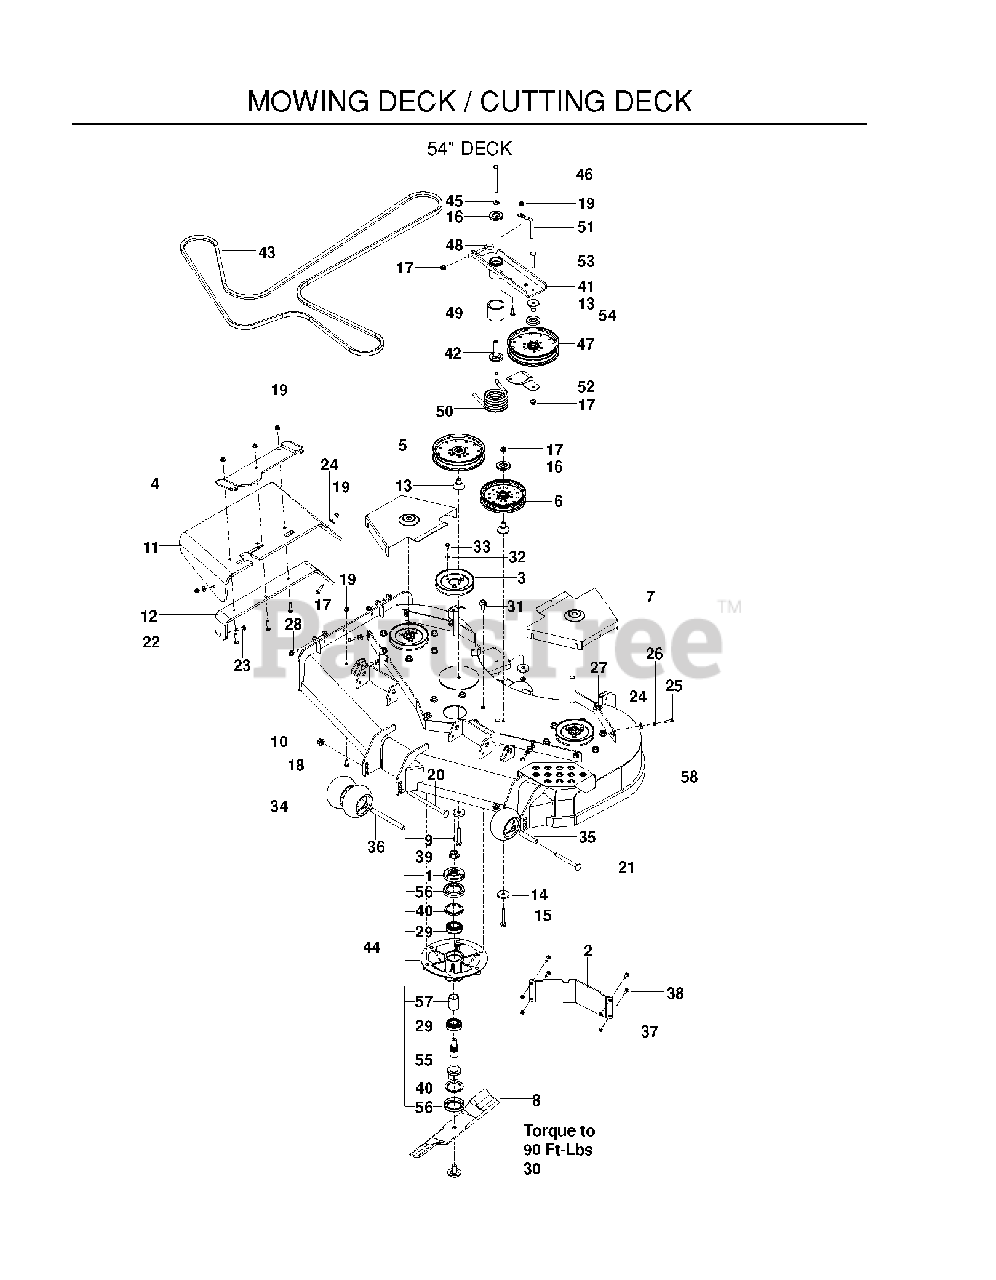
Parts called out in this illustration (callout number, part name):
1	HUB - PULLEY
2	BAFFLE, DIVERTER 54"/60" LH
3	PULLEY - 5.93 OVER PINS
4	BRKT - CHUTE MTG BLACK
5	PULLEY - 7" NARROW
6	PULLEY IDLER, 6" NARROW
7	SHIELD, BELT, 60" BLUE
9	ZERK
10	NUT, 1/2-13 HEX FLG NYLOC ZD
11	CHUTE, DISCHARGE 48-52
12	BRKT, CHUTE SUPPORT BLACK
13	BEARING, IDLER ARM
14	SPINDLE WASHER
15	HHFS 3/8-16 X 2 3/4
16	DUST SHIELD
17	NUT 3/8-16 HEX FLG NYLOC ZD
18	HHFS 5/16-18 X 3/4
19	5/16-18 NYLOC FLANGE NUT
20	RHSNB 1/2-13 X 8 GR5 ZD
21	RHSNB 1/2-13 X 4.75 GR5 ZD
22	RHSNB 5/16-18 X 1-1/2 GR 5 ZD
23	BOLT, CARRIAGE 5/16X1-1/4
24	WASHER 5/16 FLAT
25	HCS 5/16C X 1
26	WASHER 5/16 LOCK
27	U-CLIP 5/16-18 NUT RETAINER
28	HHFS 3/8-16 X 1 GRD 5 ZD
29	BEARING - 206KRR8
30	BLADE BOLT/WASHER
31	HHFS 1/2-13 X 1 GR5 ZD
32	WASH 5/16 DISC SPRING ZD
33	HCS 5/16-18 X 1/2 GR 5 ZD
34	ROLLER, GAUGE .635 BORN
35	TUBE, ROLLER AXLE
36	TUBE, ROLLER AXLE LONG
37	NUT 1/4-20 NYLOC
39	NUT FLANGE 3/4-16
40	V-RING, 55MM
41	ASSY, IDLER ARM, PZ
42	BEARING, IDLER PIVOT
43	BELT, "B", 169.75
44	SPINDLE ASM. 10"
45	WASHER, 3/8 THICK
46	HCS 3/8-16 X 4-1/2 GR 8 ZD
47	PULLEY - IDLER 7"
48	EYE BOLT, 3/8 X 4"
49	SPACER, IDLER PIVOT
50	SPRING, TORSION, IDLER
51	BELT KEEPER
52	BELT GUIDE, BLK
53	CARRIAGE BOLT 3/8-16 X
54	RHSSNB 5/16C X 1.0
55	SHAFT - SPINDLE
56	CUP - DEBRIS
57	SPACER - BEARING
